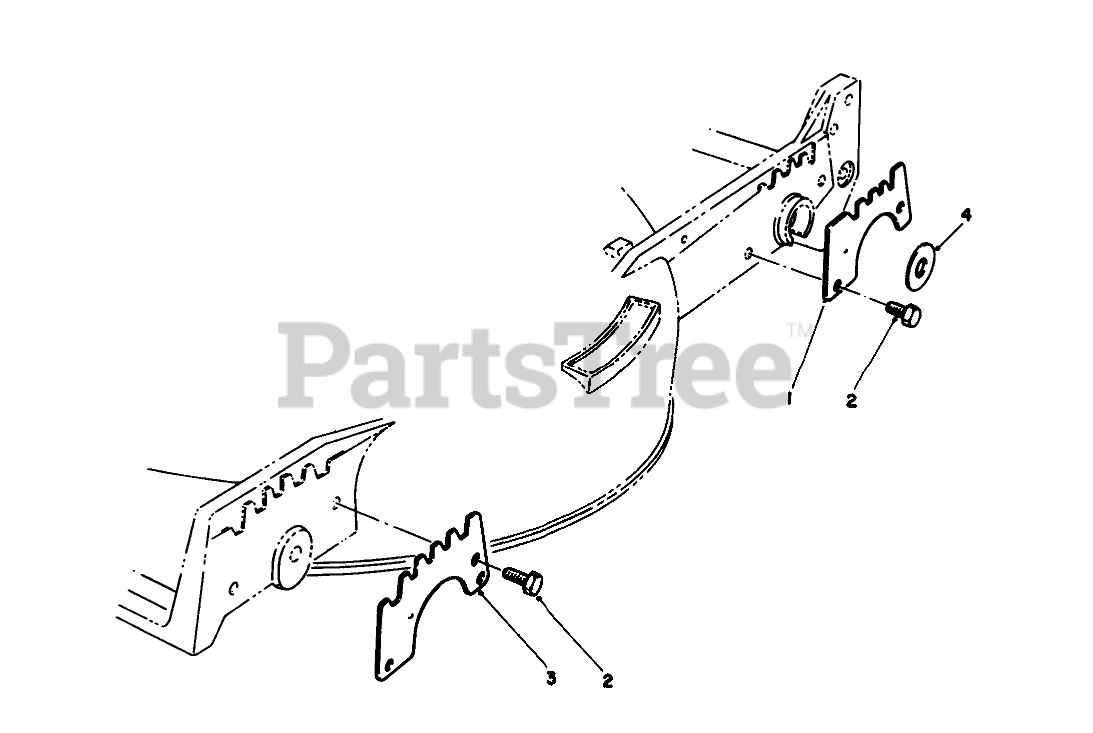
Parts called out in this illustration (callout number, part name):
1	WEAR PLATE,REAR
2	SCREW-HWH
3	WEAR PLATE
4	PIVOT WASHER
